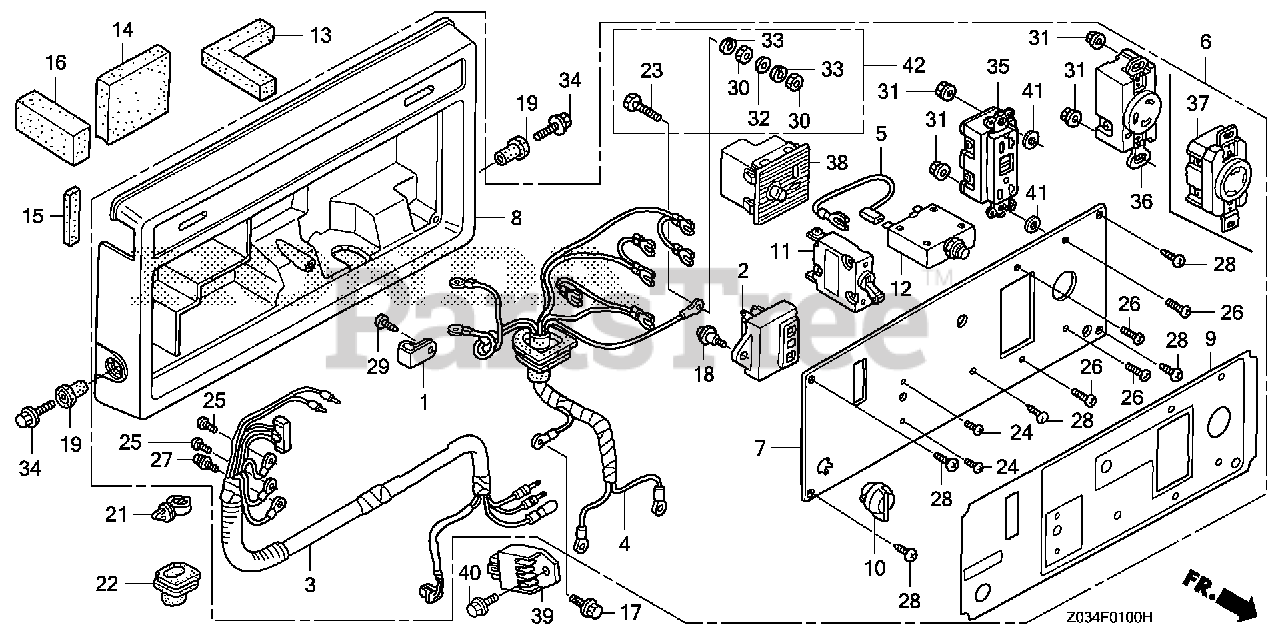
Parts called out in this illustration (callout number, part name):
1	CLAMP C, CABLE
2	IGNITION UNIT
3	WIRE HARNESS ASSY., MAIN
4	SUB-WIRE HARNESS ASSY.
5	SUB-WIRE ASSY.
6	BOX ASSY., CONTROL
6	BOX ASSY., CONTROL (NOT AVAILABLE)
7	PANEL, CONTROL
8	CASE, CONTROL (C1)
9	MARK, CONTROL PANEL
10	SWITCH ASSY., ENGINE STOP (RED)
11	BREAKER, CIRCUIT (22A)
12	PROTECTOR, CIRCUIT (20A)
13	INSULATOR (A)
14	INSULATOR (B)
15	INSULATOR (C)
16	INSULATOR (D)
17	BOLT, FLANGE (6X12) (CT200)
18	SCREW, PAN (5X13)
19	NUT, WELL (6MM)
22	GROMMET, WIRE HARNESS
23	BOLT, HEX. (6X22)
24	SCREW, PAN (3X5)
25	SCREW, PAN (3X8)
26	SCREW, PAN (4X10)
27	SCREW-WASHER (4X8)
28	SCREW, TAPPING (5X10)
29	SCREW, TAPPING (5X12)
30	NUT, HEX. (6MM)
31	NUT, FLANGE (4MM)
32	WASHER, PLAIN (6MM)
33	WASHER, SPRING (6MM)
34	BOLT, FLANGE (6X20)
35	RECEPTACLE (20A/125V)
37	RECEPTACLE (30A/125V)
38	RECEPTACLE, D.C.
39	RECTIFIER ASSY.
40	BOLT, FLANGE (6X12)
42	TERMINAL SET, GROUND
